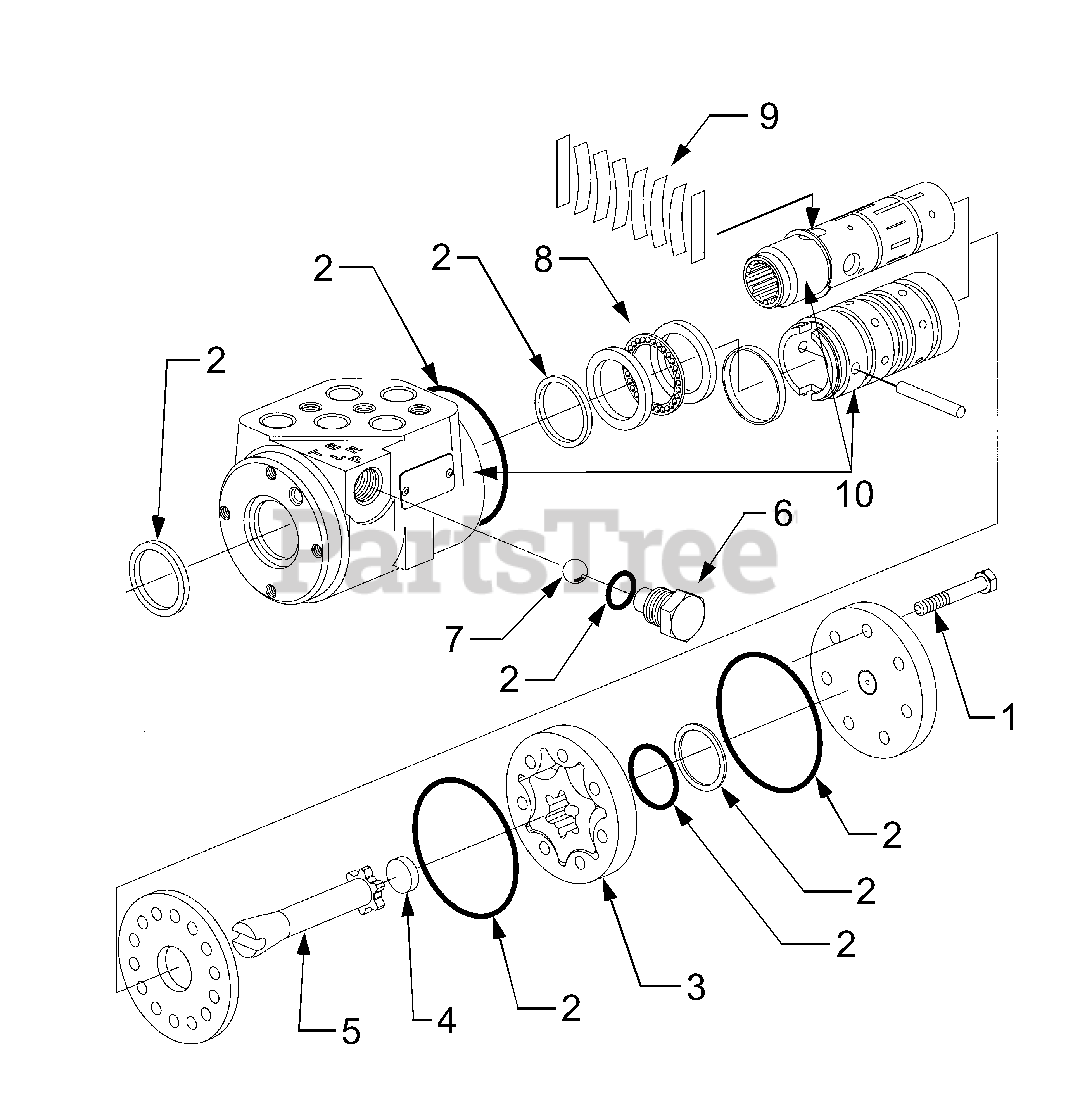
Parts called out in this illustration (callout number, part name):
1	Screw, Hex Cap, 1.57" Lg.
2	Seal Kit
3	Gerotor Assembly
4	Spacer, .240 Lg.
6	Plug, Manual Check
7	Ball, Manual Check
9	Spring Kit, Centering
10	Spool, Sleeve and Housing
